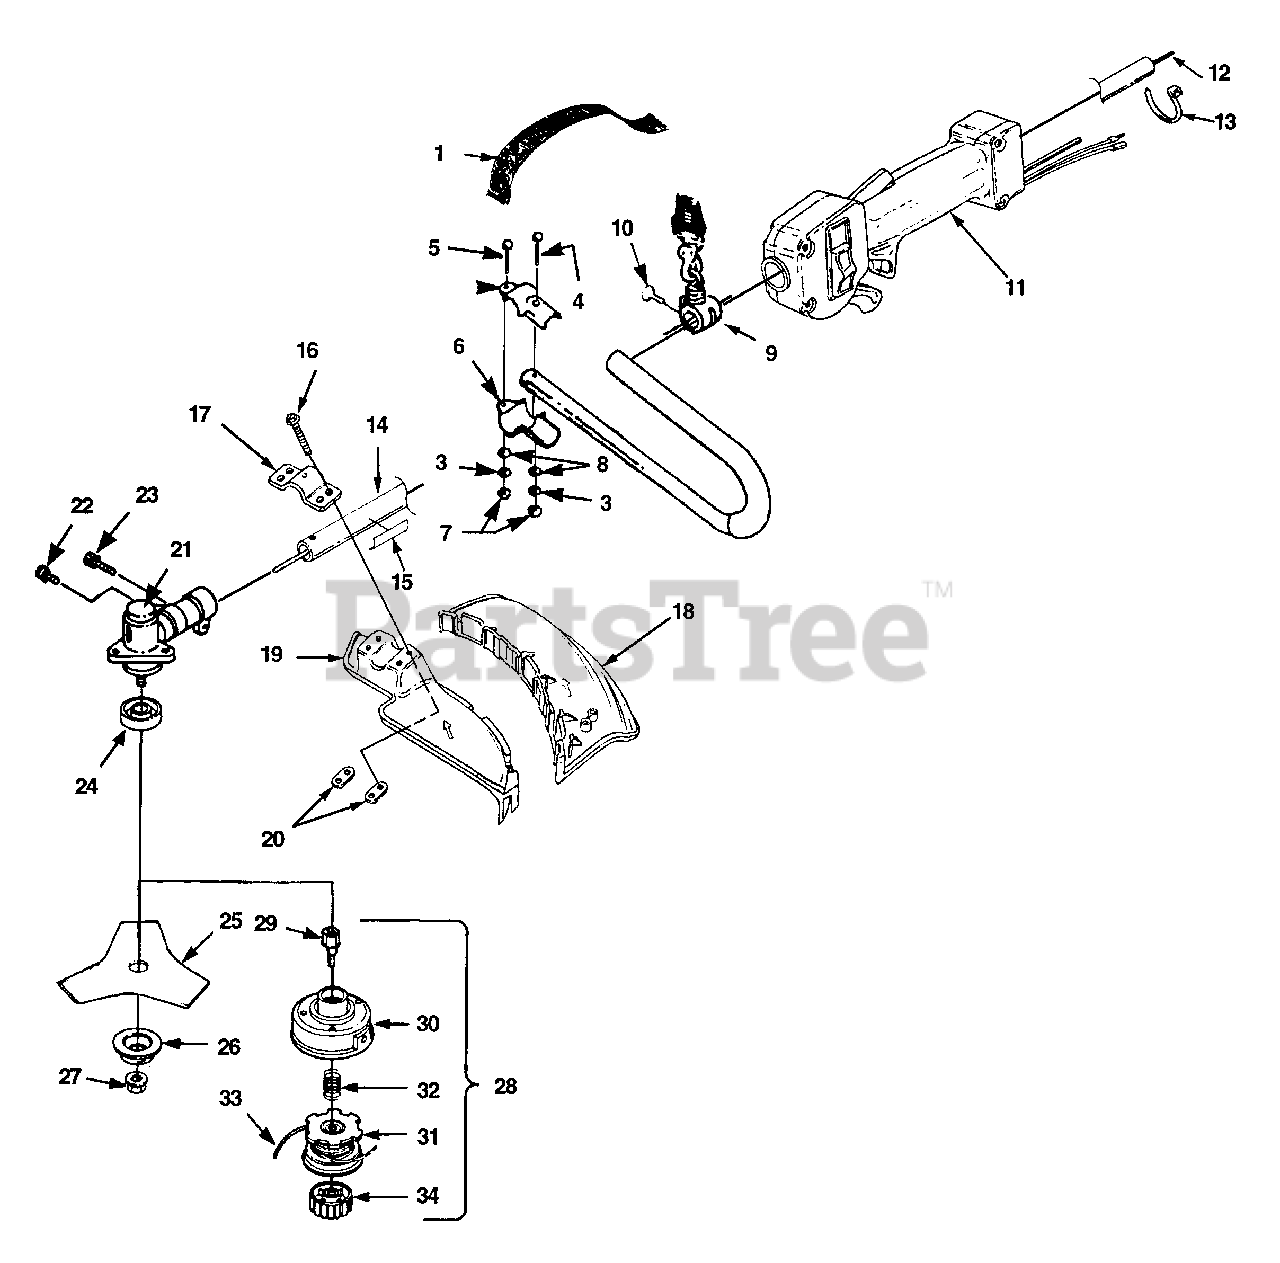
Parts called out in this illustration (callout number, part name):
1	HARNESS w/Connector
3	Washer-Lock
4	SCREW-Hex Hd. (1/4-20 X 1/2")
5	SCREW-Hex Hd. (1/4-20 X 1")
6	CLAMP-Handle Bar
7	NUT-Hex (1/4-20)
8	WASHER- Flat
9	BRACKET-Hanger
10	SCREW-Thumb (10-24 X 1/2")
11	THROTTLE & SWITCH w/Lead
12	SHAFT-Drive
13	CABLE-Tie
14	HOUSING-Drive Shaft
15	DECAL-Warning
16	SCREW-Mach. Truss Hd. (10-24 X .750)
17	CLAMP
18	STRING SHIELD
19	BLADE GUARD
20	MOUNTING PLATE
21	GEAR HEAD
22	SCREW-Sems Hex Hd. (10-24 X 1/2")
23	SCREW-Cap Socket Hd. (1/4-20 x 7/8")
24	WASHER-Flange
25	BLADE-Tri-Arc
26	WASHER-Flange
27	NUT-Hex (L.H.)
28	STRINGHEAD COMPLETE
29	CONNECTOR-Drive
30	HOUSING & EYELET (Dual Line)
31	SPOOL & STRING (Dual Line)
32	SPRING-Compression
33	LINE-Replacement (.095" Dia.) (285')
34	RETAINER-Spool (L.H.) (Red)
